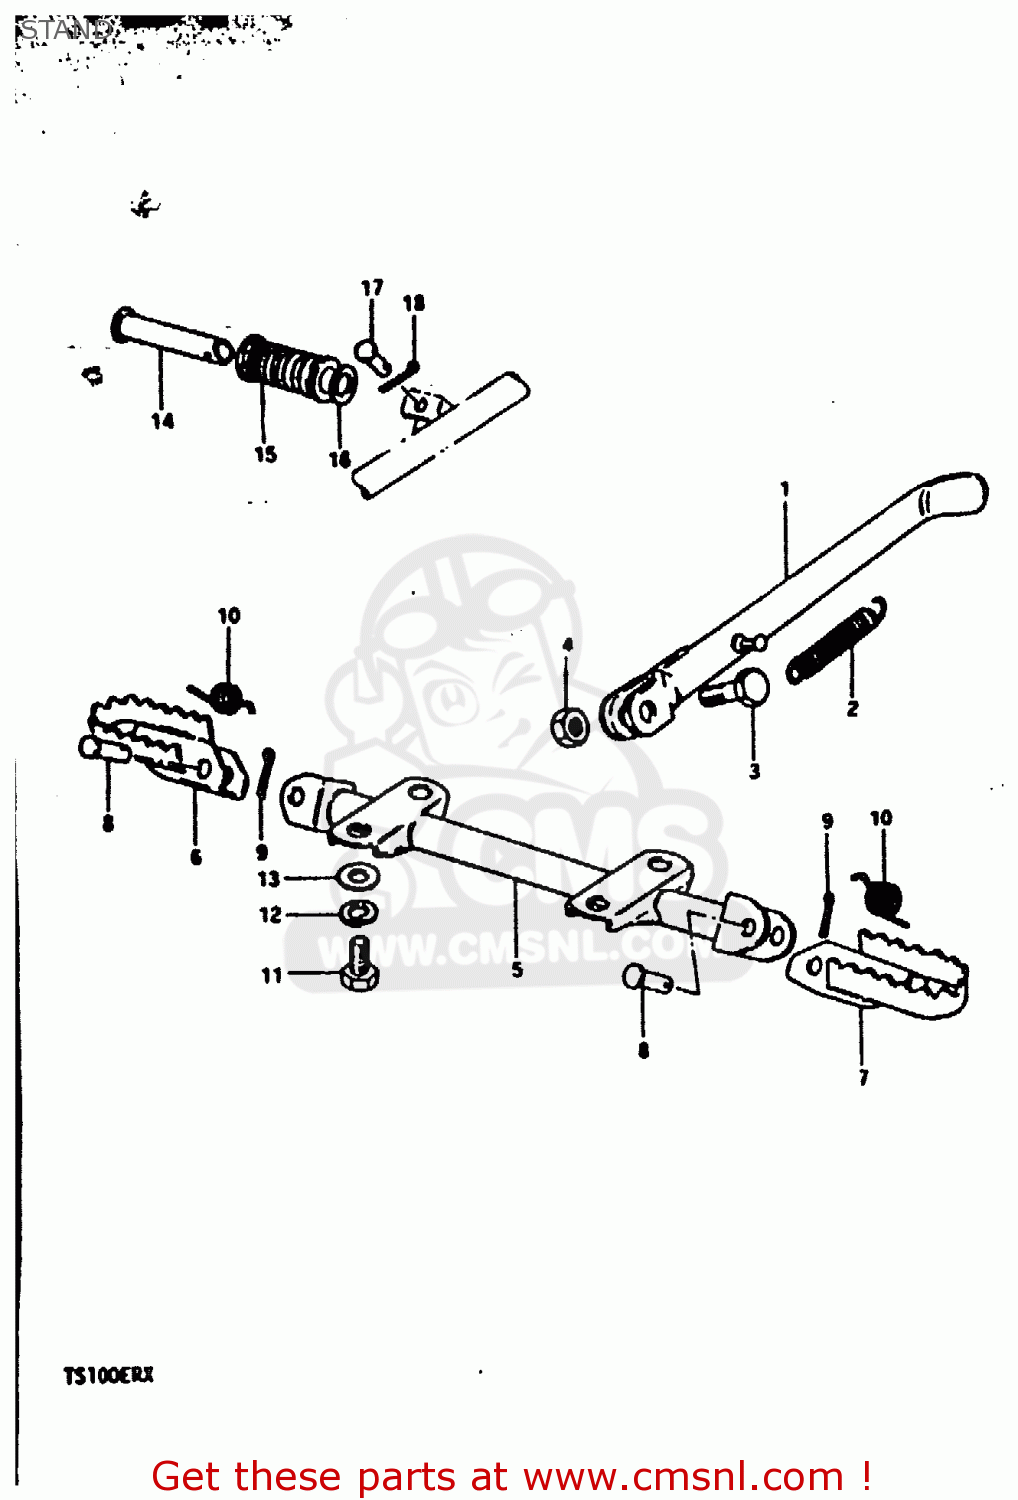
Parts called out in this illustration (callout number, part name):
1	STAND,SIDE
2	SPRING
3	BOLT(10X30)
4	NUT
5	BAR,FR FOOTREST
6	FOOTREST,FRONT
7	FOOTREST
8	PIN
9	PIN 20X20
10	SPRING
11	BOLT
12	LOCK WASHER
13	WASHER
14	BAR,FOOTREST RUBBER
15	RUBBER,PILLION FOOTREST
16	WASHER (19.5X32X2)
17	PIN
18	PIN 20X20
